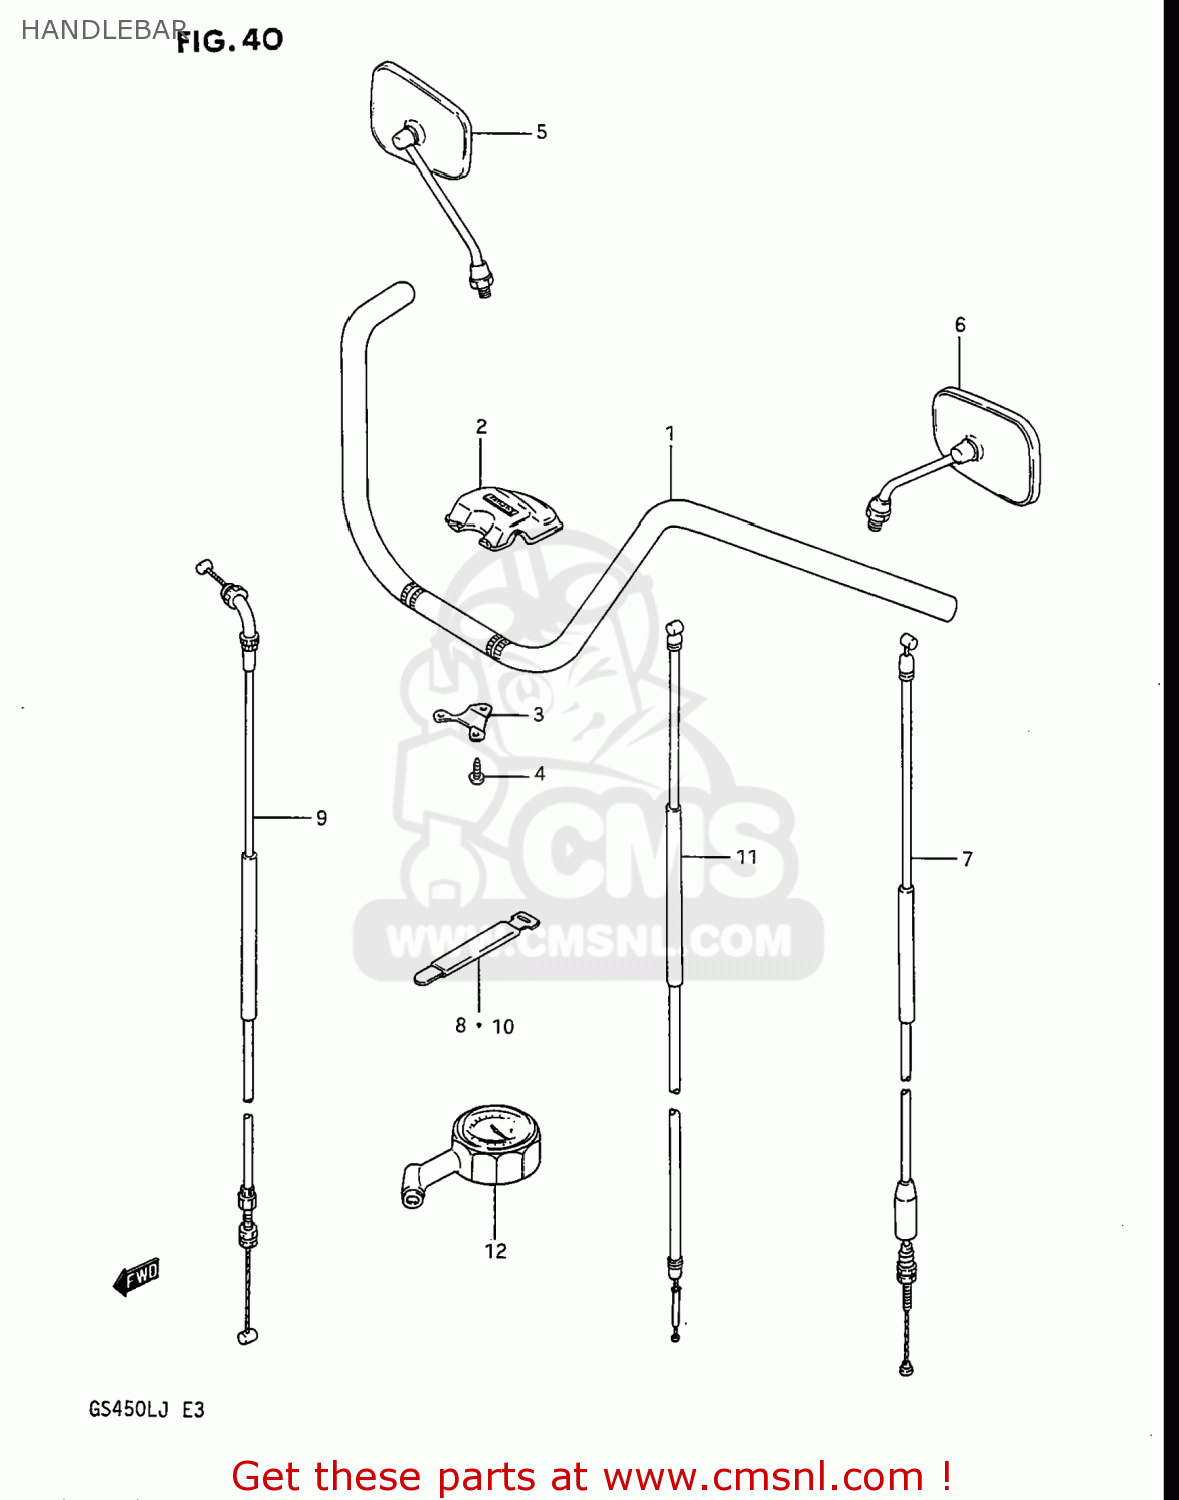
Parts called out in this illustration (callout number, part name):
1	HANDLEBAR,RIGHT
2	COVER,STEERING HEAD
3	BRACKET,HEAD COVER
4	SCREW
5	MIRROR ASSY,RR VIEW,R
6	MIRROR ASSEMBLY,LEFT
7	CABLE ASSY,CLUTCH
8	CLAMP
9	CABLE ASSY,THROTTLE NO.1
10	CLAMP
11	CABLE ASSEMBLY,STARTER
12	GAUGE ASSY,AIR PRESSURE
